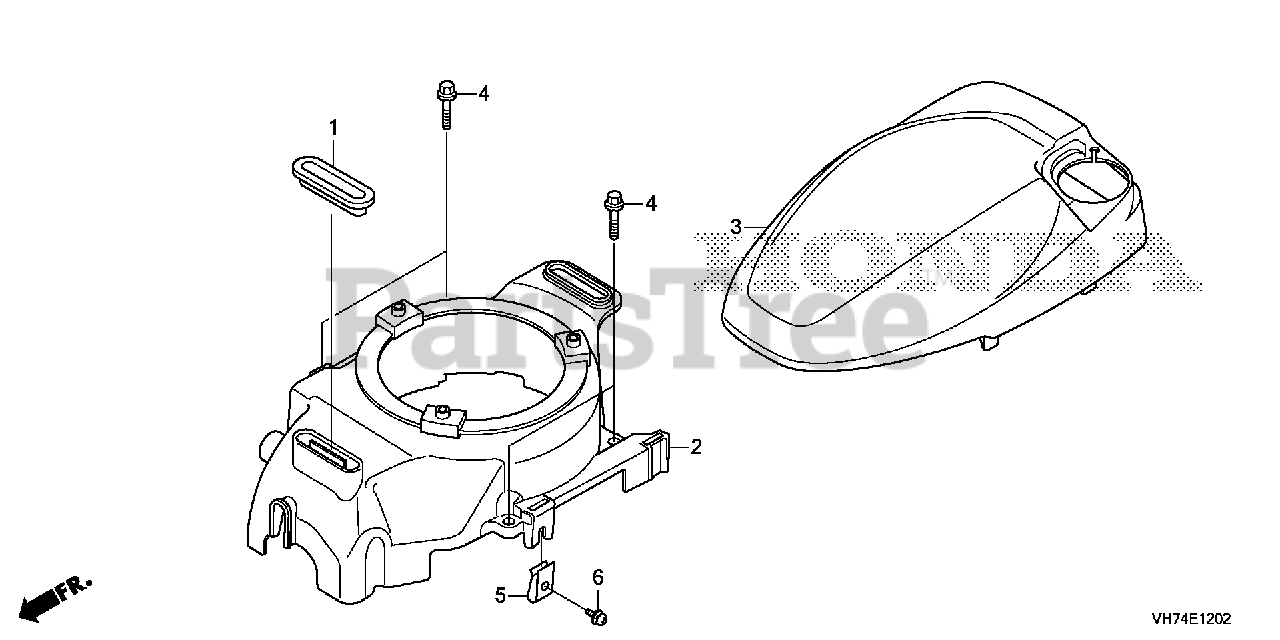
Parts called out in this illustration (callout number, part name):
1	RUBBER A, TANK MOUNTING
2	COVER, FAN
3	COVER, TOP *R280* (POWER RED)
4	BOLT, FLANGE (6X23)
5	NUT, SPRING (5MM)
6	SCREW-WASHER (5X8)
